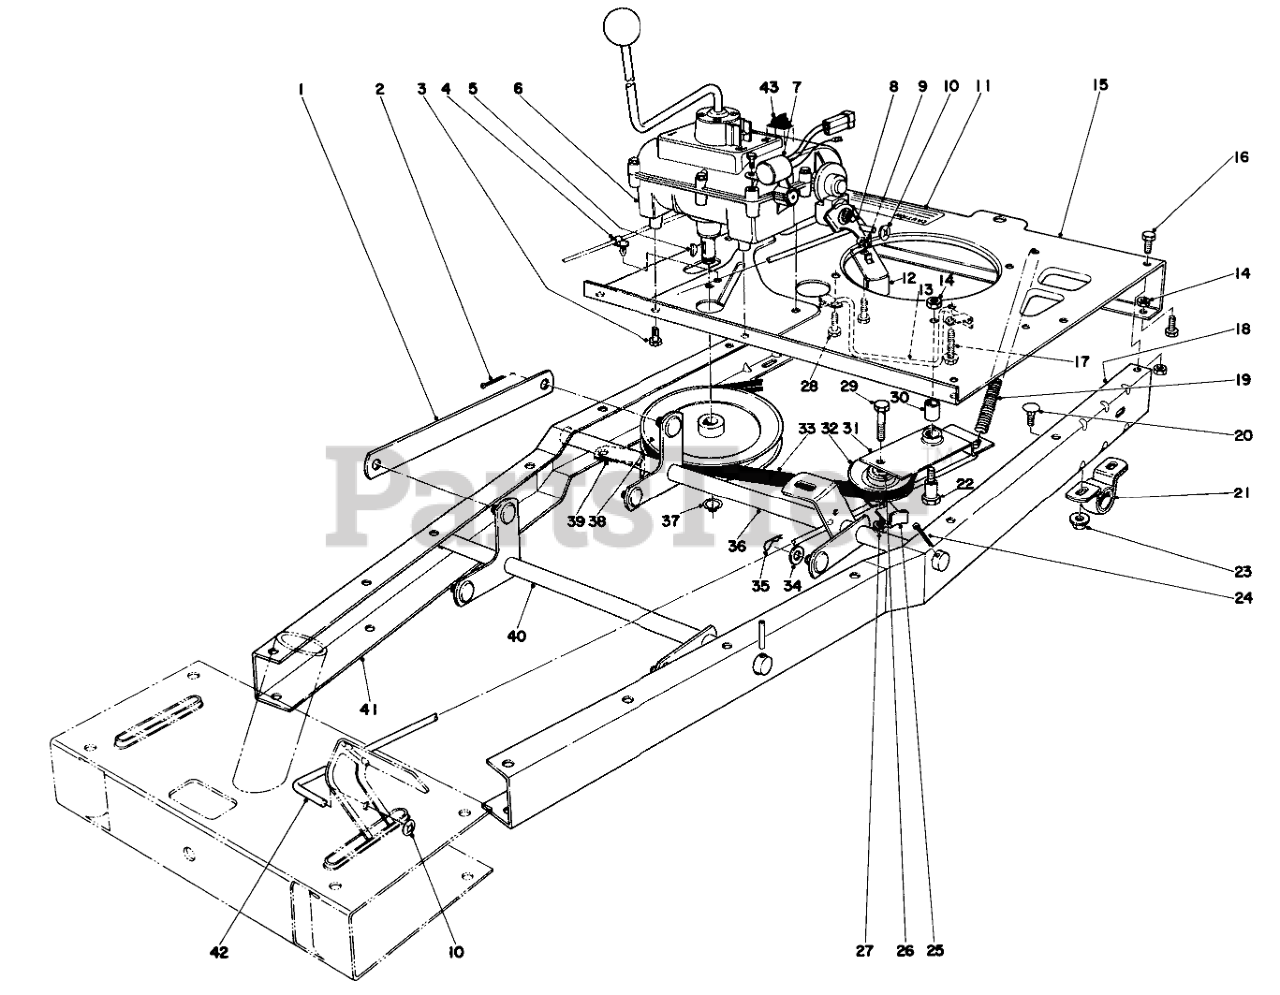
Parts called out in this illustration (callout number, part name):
1	Linkage-Height Adj.
2	PIN-COTTER
3	5/16-18 X 5/8 SEMS SC
4	Cable Holder
5	KEY-WOODRUFF
6	Transmission
7	Control Module
8	Brake Return Spring
9	WASHER-PLAIN
10	PUSH ON SPEED NUT 1/4
11	Decal
12	Belt Retainer
13	Belt Guide
14	NUT-LOCK, CONE
15	Engine Mounting Plate
16	SCREW-HH
17	SCREW-HWHTF
18	Frame Chanel, L.H.
19	Clutch Tension Spring
20	SCREW-CARR
21	PILLOW BLOCK
22	CLUTCH PIVOT BOLT
23	NUT-HF
24	PIN-COTTER
25	RETAINER-BELT
26	Washer
27	NUT-LOCK, CONE
28	Sems Screw
29	SCREW-HH
30	BUSHING
31	Traction Idler (Incl. Ref. #28)
32	PULLEY-IDLER
33	V-BELT
34	WASHER-FLAT
35	PIN-COTTER
36	Height Adjustment
37	RING-SNAP, EXTERNAL
38	PULLEY
39	TRANS BELT RET B
40	FRONT LIFT WA B
41	Frame Channel R.H.
42	CLUTCH ROD
43	Wire & Cable Tie
